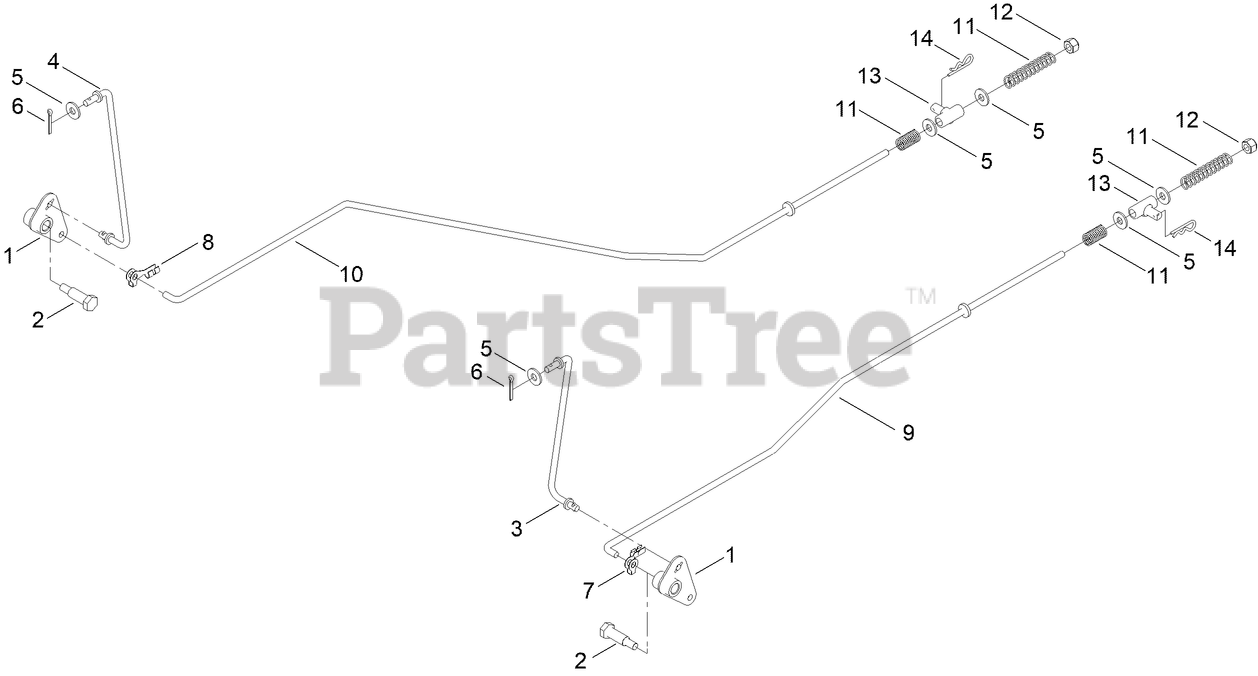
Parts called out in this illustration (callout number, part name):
1	BELLCRANK
2	BOLT - SHOULDER
3	LINK-BRAKE, LH
4	LINK-BRAKE, RH
5	WASHER
6	PIN-COTTER
7	CLIP, ROD, LH, 7L, 1/4IN
8	CLIP, ROD, RH, 7R, 1/4IN
9	ROD-BRAKE LH
10	ROD-BRAKE, RH
11	SPRING-COMPRESSION
12	NUT-LOCK, NI
13	MOUNT-PIVOT
